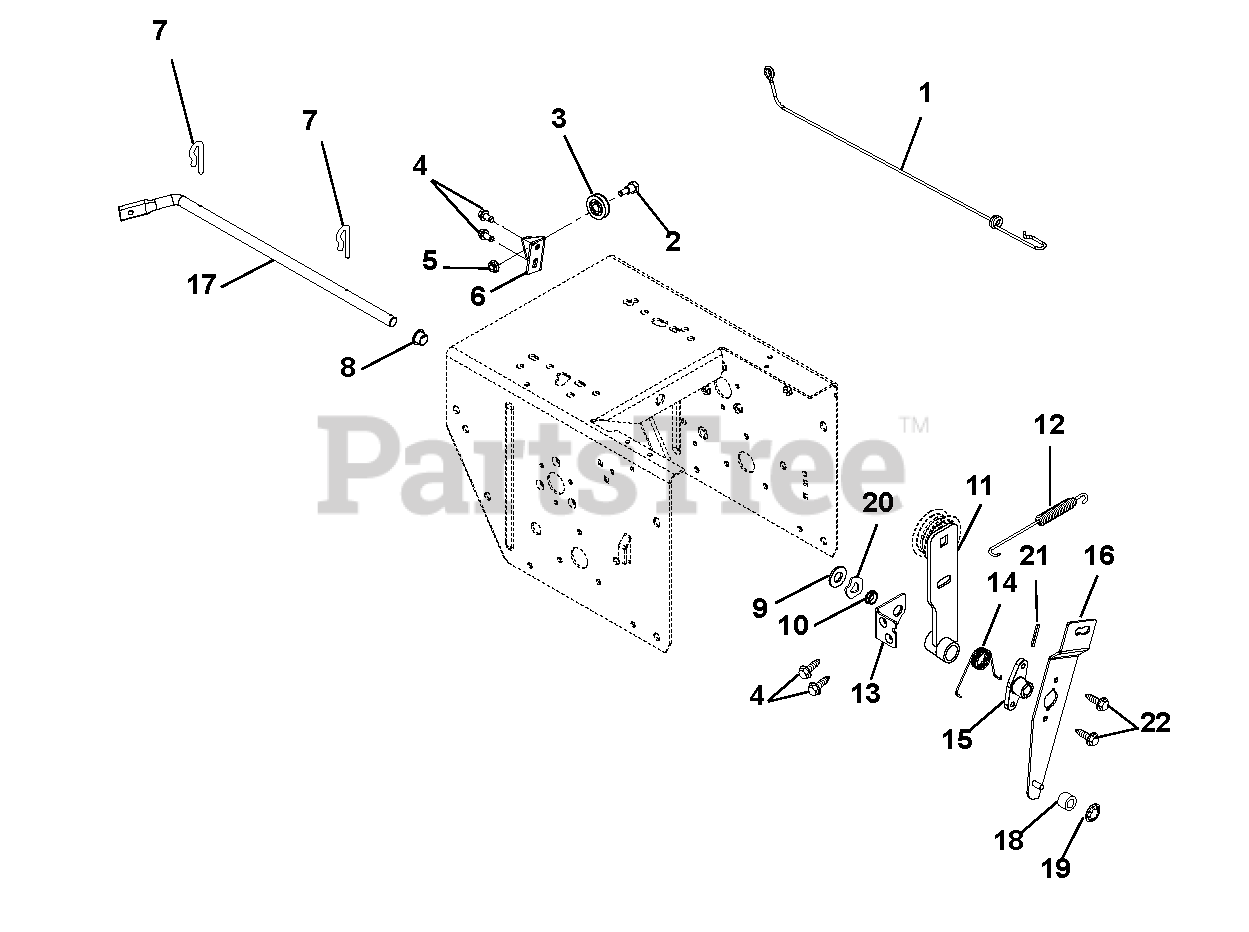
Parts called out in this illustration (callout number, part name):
2	Bolt, Shoulder
3	Pulley, Cable
4	Screw, Tapping Hex Washer Head Thread Rolling .25-20 x .50
5	Nut, Locking Top Flange .25-20
6	Bracket, Cable Pulley
7	Clip, Spring
8	Bushing, Polyliner
9	Washer, Flat Steel .531 x 1.06 x .095
10	Bushing, Flange
11	Arm, Idler – Traction
13	Bracket, Support
15	Hub, Brake Arm
16	Arm, Idler – Attachment
17	Arm, Attachment
18	Bushing,Sleeve
19	Ring, Retaining External .250 x .010
20	Wave Washer
21	Pin, Roll .125 x 1.00
22	Screw, Tapping Hex Washer Head Thread Rolling .25-20 x .75
